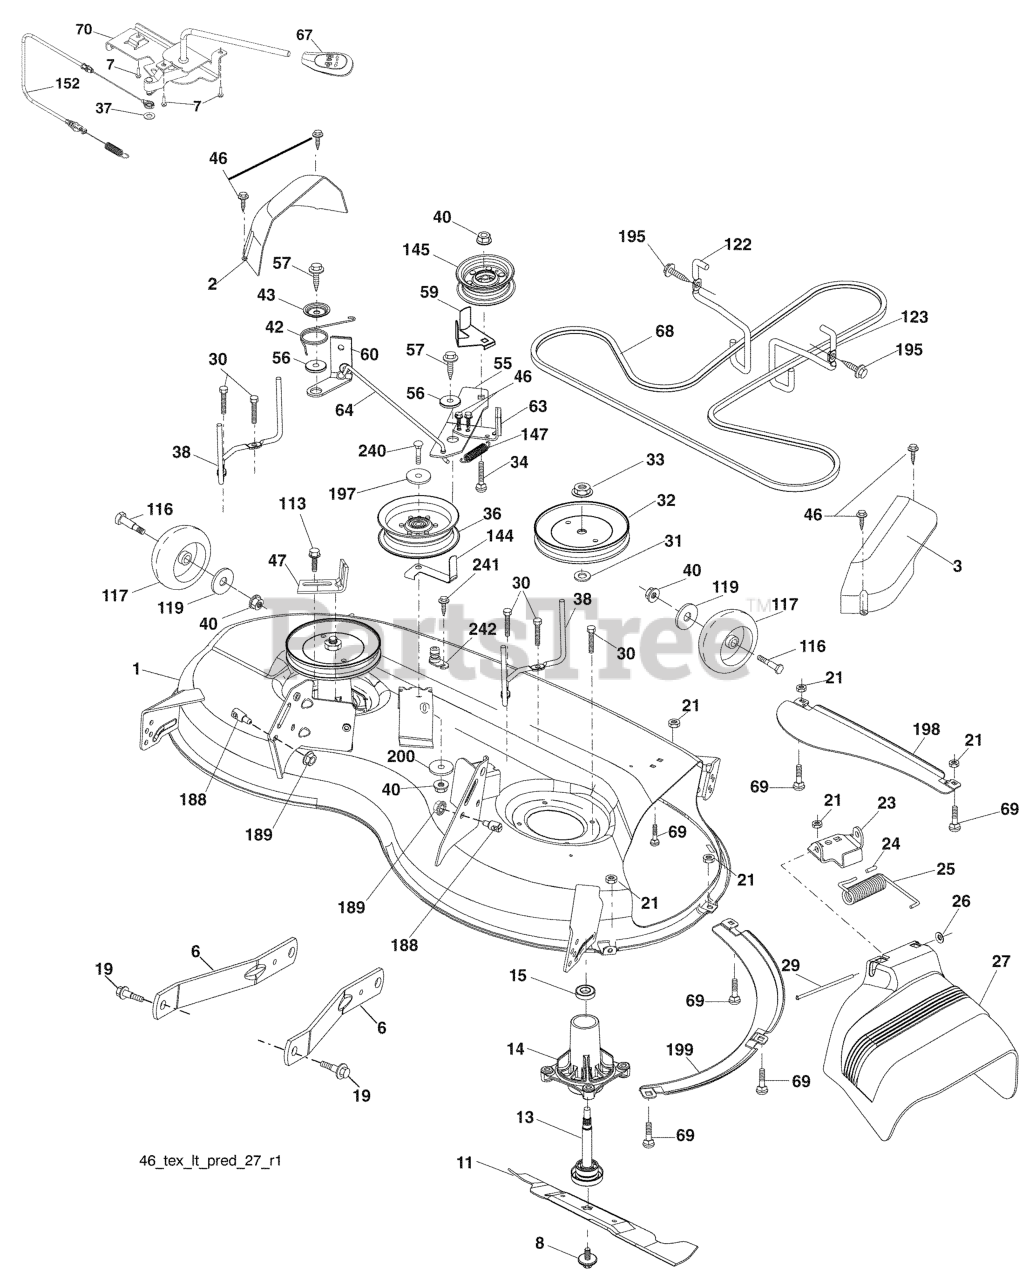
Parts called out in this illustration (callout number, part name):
1	DECK.WELDMENT.46"
2	COVER.MANDREL.RH.46"
3	COVER.MANDREL.LH.46"
6	ARM.SUSPENSION.MOWER.R
7	SCREW.#10 X 0.750.BOS
8	BOLT.WASHER.ASM.7/16-2
11	BLADE.MOWER.46".HI.LIFT
13	SHAFT.ASM.MDRL.N/GREASE.38
14	RP.HOUSING.MANDREL.4PT.
19	BOLT.SHOULDER
21	LOCKNUT
23	BRKT.DEFLECTOR.38"2005+
24	CAP-SLEEVE LT
25	SPRING.TORSION.DEFLECT
26	NUT PUSH M
27	SHIELD.DEFLECTOR.MOWER.46"BLAC
29	ROD.HINGE
30	SCREW, WASHER HEAD
31	WASHER.SPACER.MANDREL
32	PULLEY.MANDREL.5.438.PD
33	NUT.FLANGE.LOCK.TOP
34	BOLT.3/8-16X1.50
36	PULLEY.IDLER.2006
37	WASHER
38	KEEPER.BELT.LH.MANDREL
40	NUT LOCK FLG 3/8-16 UNC
42	SPRING.TORSION.BRAKE
43	SRPING.TORSION.RETAINE
46	SCREW.1/4-20X5/8
47	BRKT.CLUTCH.CABLE
55	IDLER.ARM
56	SPACER.RETAINER
57	SCREW 3/8-16X1
59	GUARD, BELT
60	ARM BRAKE MOWER RH 38"
63	ARM BRAKE MOWER
64	LINKAGE BRAKE
67	HANDLE.CLUTCH.CABLE.LT
68	V-BELT
69	BOLT
70	CLUTCH.ASM.CABLE.HUSQ.TEX
113	BOLT.5/16HEX.WHS.HD
116	BOLT.SHOULDER.3/8-16X3-5/8.
117	RP WHEEL. GUAGE RALLY
119	WASHER
122	KEEPER BELT ENGINE LH
123	KEEPER BELT RH
144	KEEPER.BELT.MOWER
145	PULLEY.IDLER.48"PRIMARY
147	SPRING RETURN
152	CABLE CLUTCH MANUAL W/SPR.
188	STUD.FASTNER.W/ANTI-ROTATE
189	NUT LOCK HEX FLANGE 5/16-18
195	SCREW, 3/8-16X3/4
197	WASHER
198	BAFFLE CENTER FRONT
199	BAFFLE FRONT RH
200	WASHER.13/32 X 1 X 1/2.11GUARD
240	BOLT-HEX EAK
241	SCREW.TT.#10-32X.5.3/8.FLANGE
242	PORT.WASHOUT
